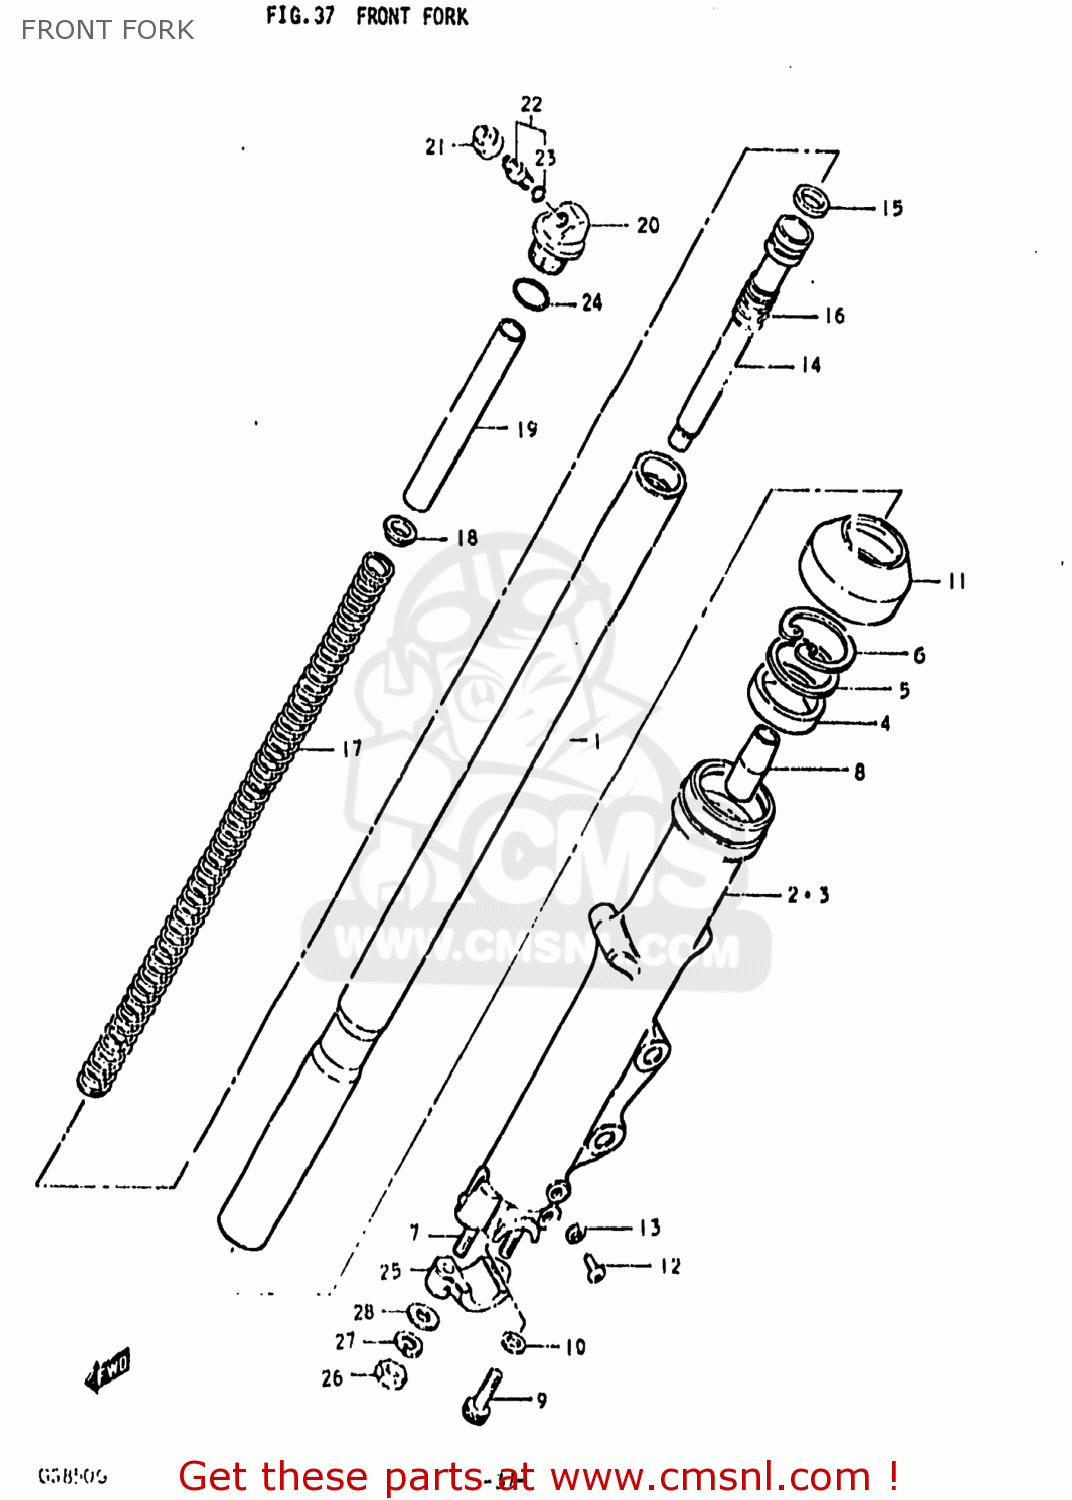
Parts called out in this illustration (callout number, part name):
0	DAMPER ASSEMBLY,LEFT
1	TUBE,FORK,INNER
2	TUBE,FORK,OUTER,RIGHT
3	TUBE,FORK,LEFT,OUTER
4	OIL SEAL,FRONT FORK
5	WASHER. FRONT FORK
6	CIRCLIP,FORK OIL SEAL
7	STUD BOLT
8	PIECE,OIL LOCK
9	BOLT,FORK CYLINDER(10X25)
10	GASKET (NAS)
11	SEAL,DUST
12	SCREW
13	GASKET,DRAIN,PLUG (NAS)
14	CYLINDER,FRONT FORK
15	RING,PISTON
16	SPRING,REBOUND
17	SPRING,FRONT FORK
18	GUIDE,FRONT FORK SPRING C
19	SPACER,SPRING
20	CAP
21	CAP,VALVE
22	VALVE
23	O RING
24	O RING
25	HOLDER,AXLE
26	NUT (8MM)
27	LOCK WASHER
28	WASHER
